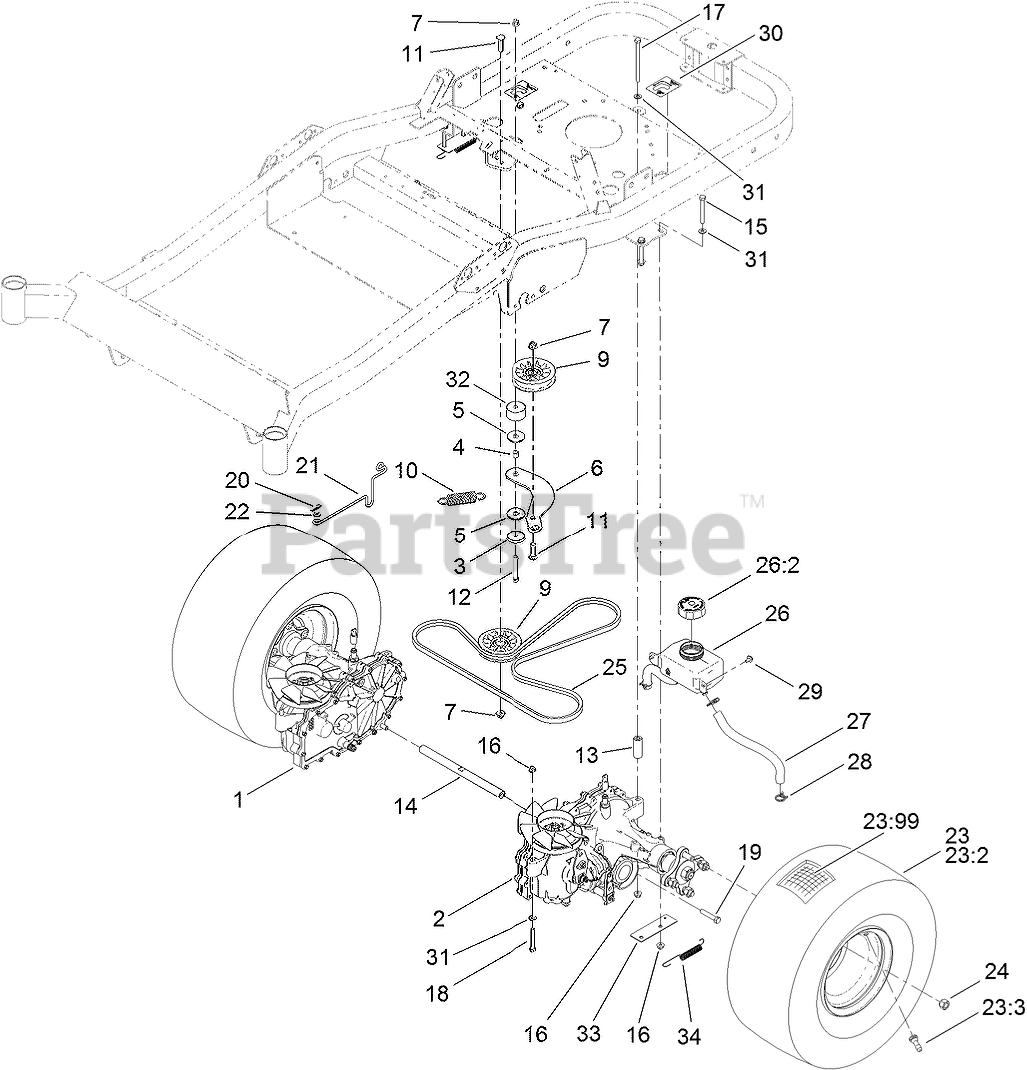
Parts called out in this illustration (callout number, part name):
1	RH HYDRO TRANSMISSION ASM
2	LH HYDRO TRANSMISSION ASM
3	WASHER-PLAIN
4	SPACER
5	WASHER-FRICTION, COMPOSITE
6	ARM-IDLER
7	NUT-HF, NI
9	PULLEY-IDLER, FLAT
10	SPRING-EXTENSION
11	SCREW-CARR
12	SCREW-HH
13	SPACER-HYDRO
14	SHAFT-CROSS, HYDRO
15	SCREW-HH
16	NUT-HF, NI
17	SCREW-HH
18	SCREW-HH
19	SCREW-HH
20	PIN-COTTER
21	ROD-BYPASS
22	WASHER-FLAT
23	WHEEL AND TIRE ASM
23:2	TIRE-TURFMASTER
23:3	STEM-VALVE
23:99	Tube-Inner
24	NUT-LUG
25	V-BELT
26	HYD RESERVIOR ASM
26:2	CAP-RESERVOIR, HYD
27	HOSE-OVERFLOW
28	CLAMP-HOSE
29	SCREW-HHFTF
30	DECAL-BYPASS
31	WASHER-PLAIN
32	SPACER
33	PLATE-SPRING
34	SPRING-EXTENSION
